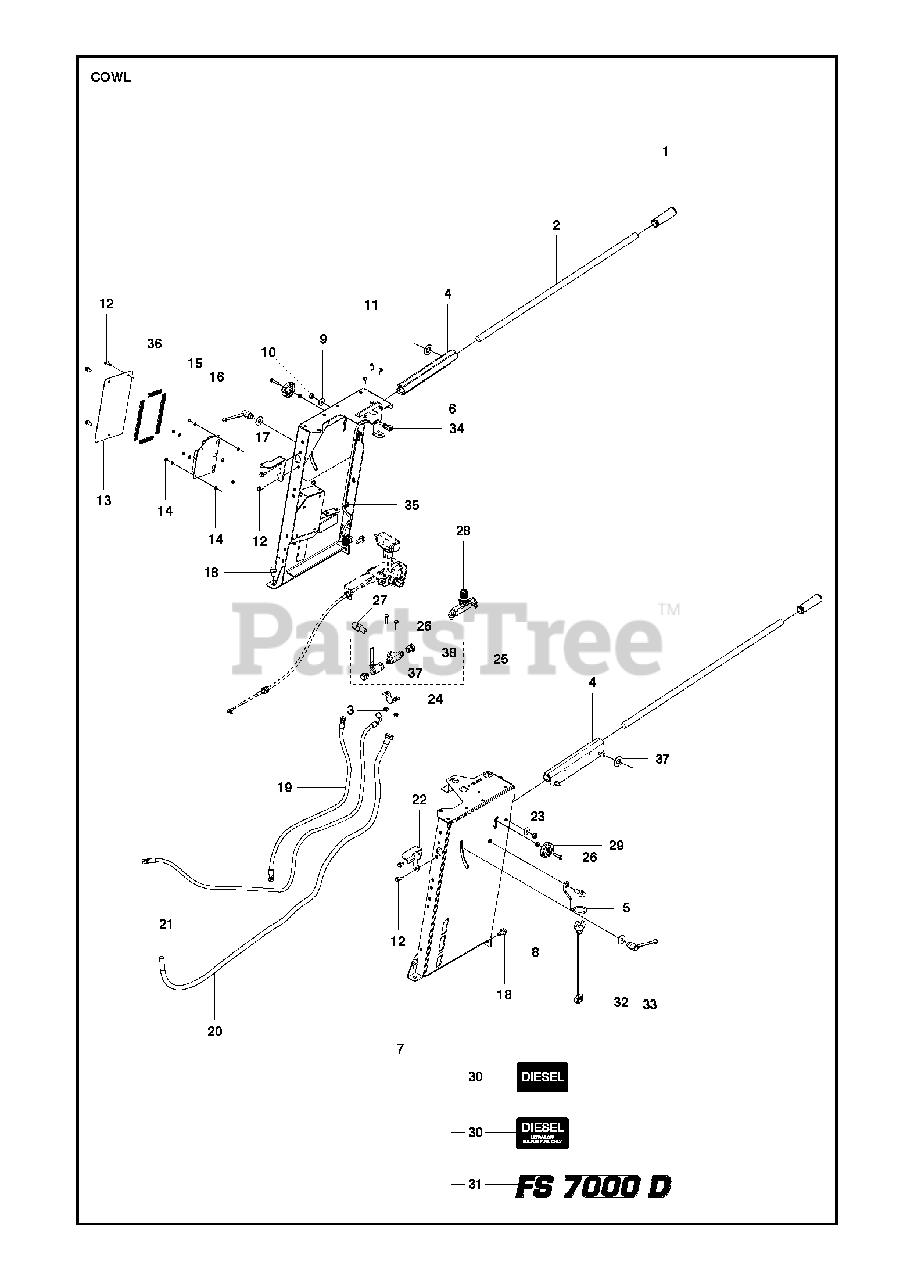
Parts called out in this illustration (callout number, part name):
9	WASHER
11	SCREW IHCSFM
23	HEXAGON NUT FLANGE
29	TURNING KNOB
